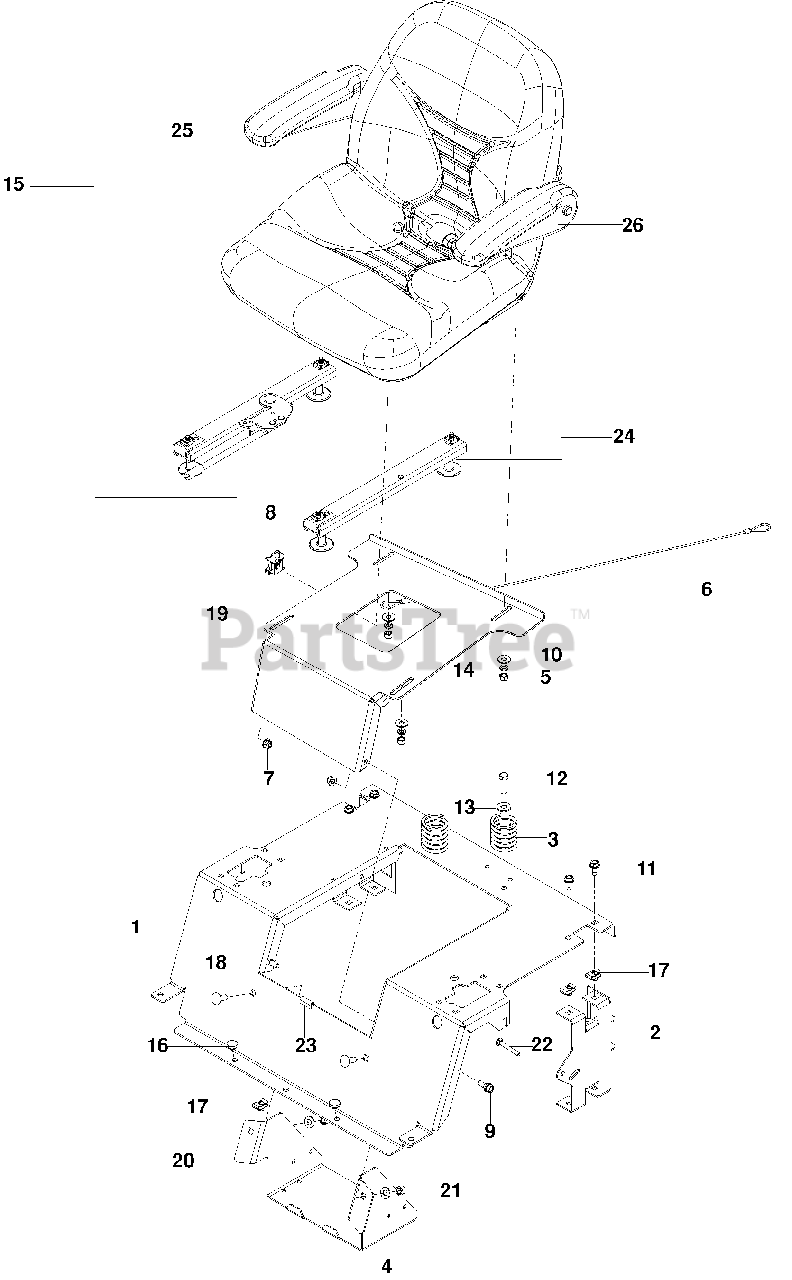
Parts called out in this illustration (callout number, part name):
1	SUPPORT, SEAT ORG
2	SUPPORT, REAR SEAT BLK
3	SPRING, SEAT
4	WASHER 3/8 SAE FLAT
5	NUT 5/16-18 HEX NYLOC
6	LANYARD, SEAT
7	NUT 5/16-18 FLANGE NYLOC
8	SWITCH, SEAT
9	BOLT 5/16-18 HEX HD SHLDR
10	WASHER 5/16 STD FLAT
11	BOLT 5/16-18 x 3/4THD FRM
12	HCS 3/8-16 x 11/4
13	WASHER 3/8 FLAT STD
14	WASHER 5/16 SLW
15	SEAT
16	GROMMET, BUMPER
17	RETAINER, U TYPE
18	RHSNB 3/8-16 x 1
19	PAN, SEAT ORG
20	BOX, BATTERY BLK
21	NUT 3/8-16 HEX NYLOC
22	RHSNB 5/16-18 x 2 1/2
24	SEAT RAIL SET
25	ARM REST RT
26	ARM REST LT
